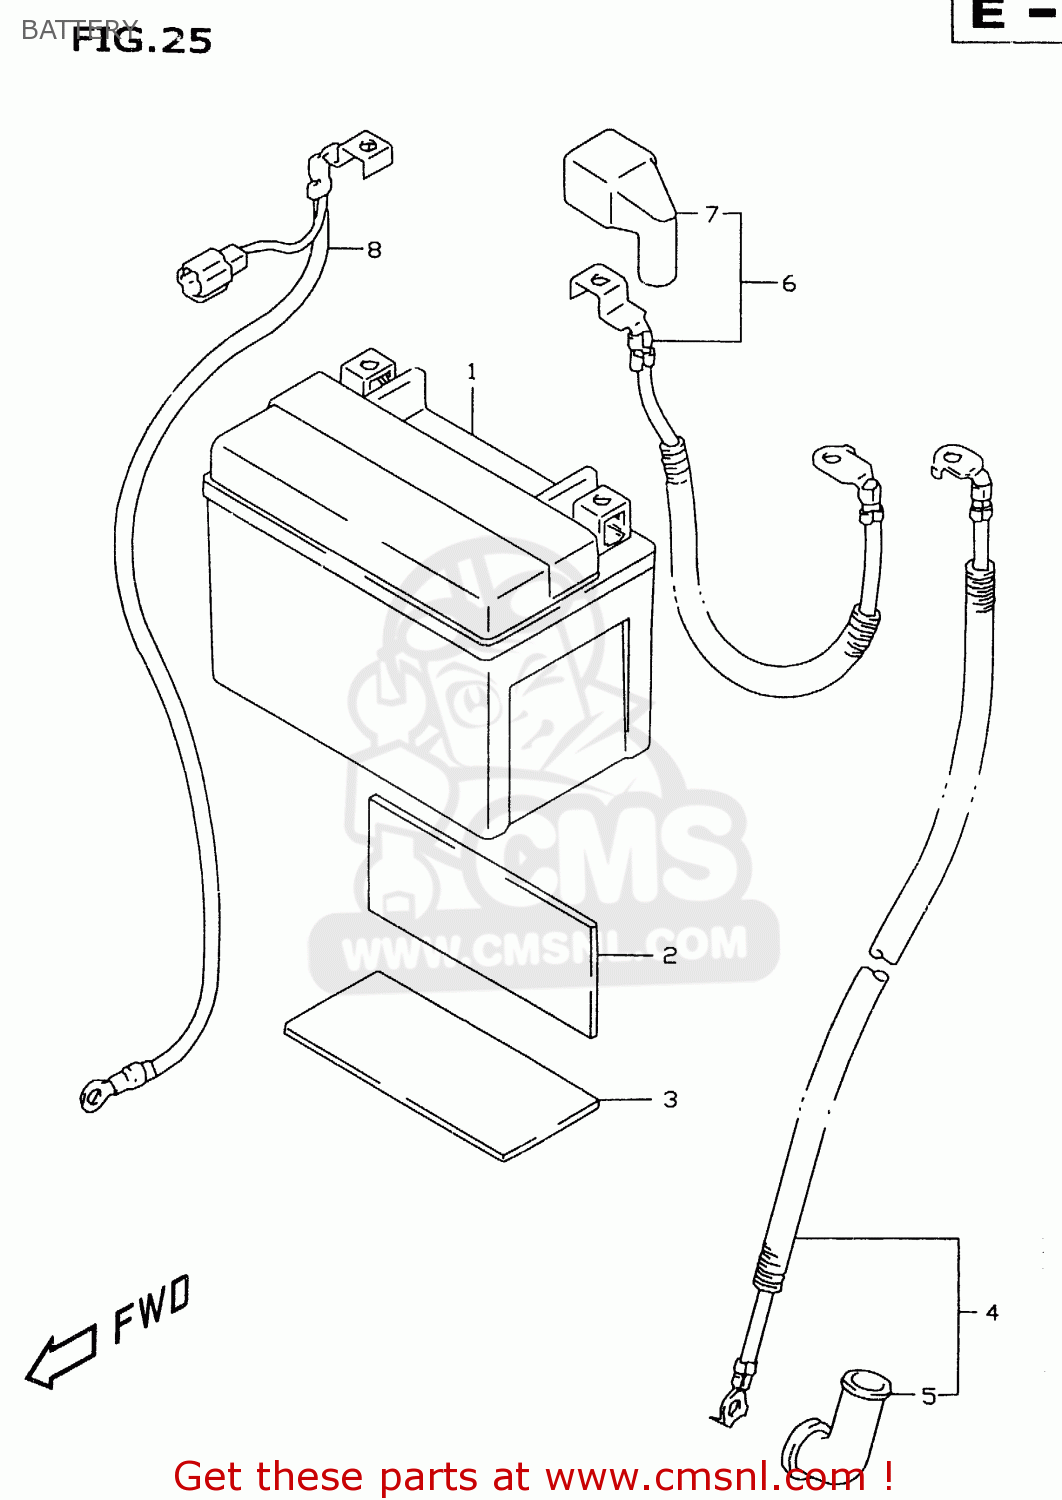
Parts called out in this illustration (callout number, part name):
1	BATTERY ASSEMBLY (12V) FTX
2	PROTECTOR(170X95X3.0)
3	CUSHION,BATTERY(90X45X18)
4	WIRE,STARTER MOTOR LEAD
5	CAP,STARTER MOTOR LEAD
6	WIRE,BATTERY PLUS LEAD
7	CAP,BATTERY PLUS TERMINAL
8	WIRE,BATTERY MINUS
